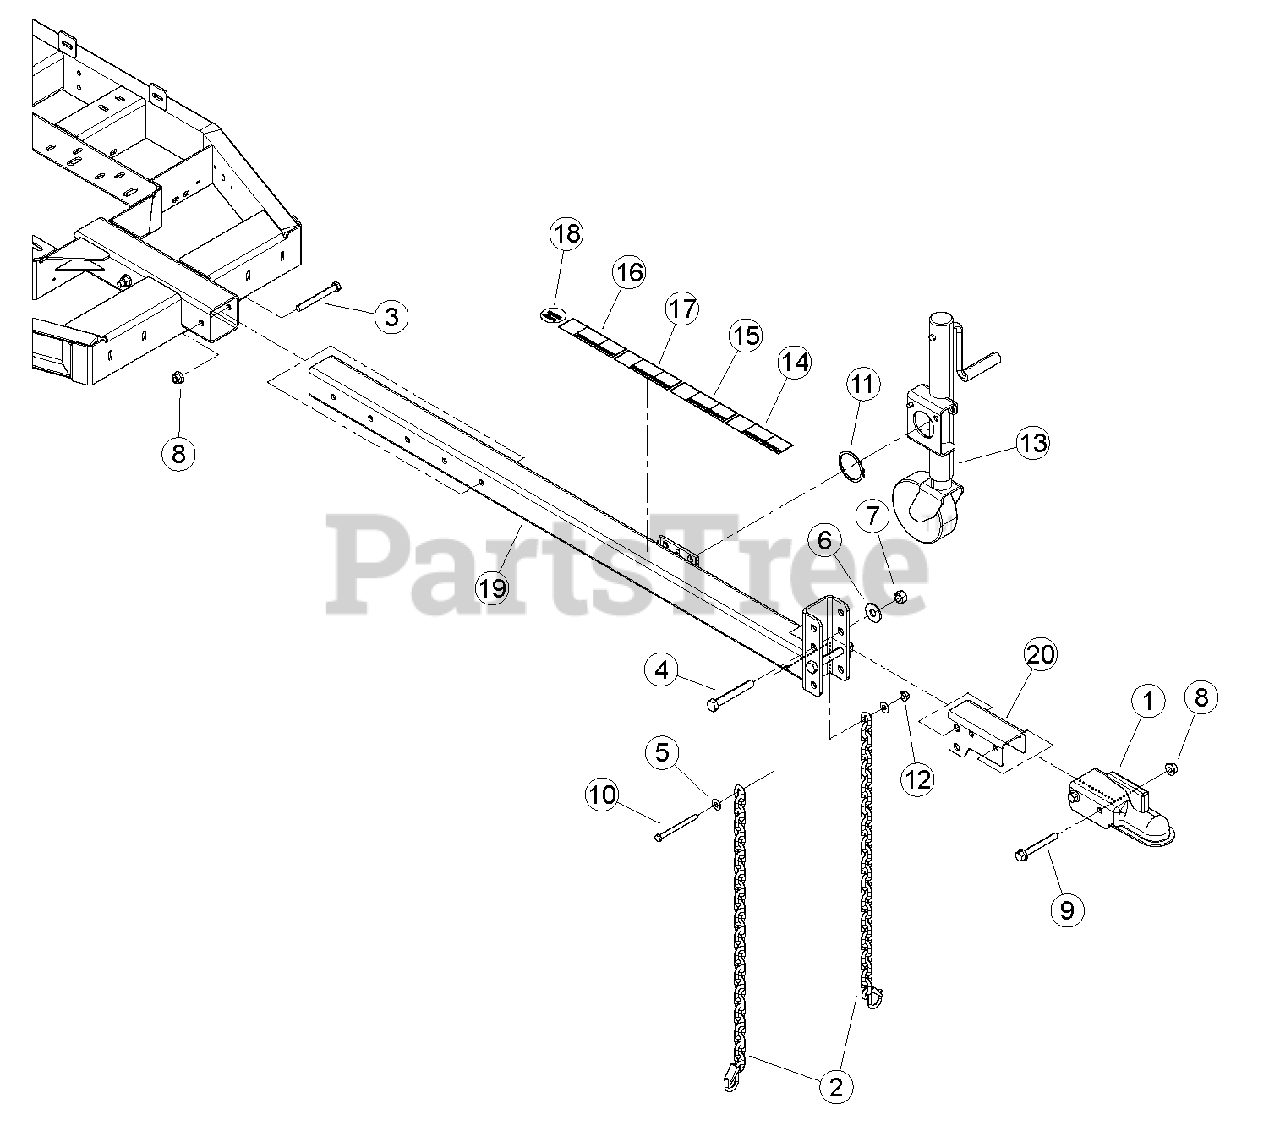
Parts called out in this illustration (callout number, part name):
1	COUPLER, 2 IN
2	CHAIN, SAFETY 5000 LB W/ LATCH
3	BOLT, 1/2 X 4-1/2" GR5 HHCS NC ZP
4	BOLT, 5/8 X 4-1/2 HEX HD G5 ZP
5	WASHER, 3/8" FLAT ZP
6	WASHER, 5/8" FLAT ZP
7	NUT, 5/8" CENTERLOCK ZP GR5
8	NUT, 1/2-13 NYLOCK FLANGE
9	BOLT, 1/2-13 X 4 HWH GR5 CZP
10	BOLT, 3/8 X 4-1/2" HHCS GR5 NC ZP
11	SNAP RING, 2-1/2 EXTERNAL
12	NUT, 3/8-16 NYLOCK FLANGE
13	JACK, PIVOTING W/ SWIVEL CASTOR
14	DECAL, SAFETY CHAINS
15	DECAL, TRAILER ELECTRICAL
16	DECAL, CHECK WHEELS
17	DECAL, SAFE COUPLING
18	DECAL, NATM COMPLIANCE
19	WELDMENT, HITCH POLE W/PLATE
20	MOUNT, COUPLER
